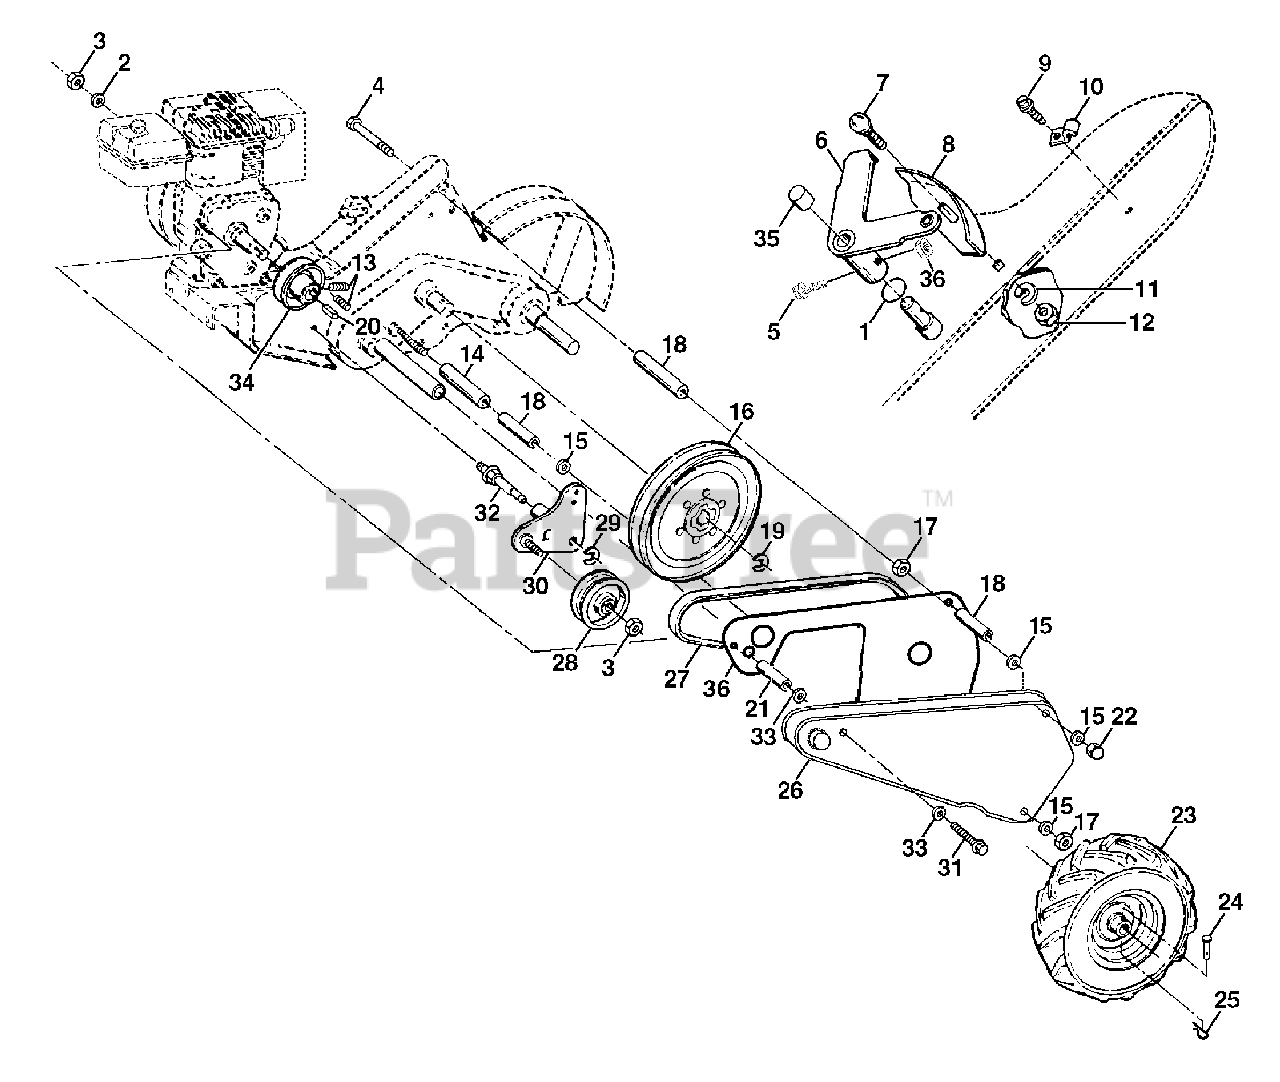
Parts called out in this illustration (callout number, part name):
2	Washer, Lock 3/8
3	Nut, Hex 3/8-16
4	Bolt, Hex Head 5/16-18 x 4-1/2
6	Lever, Shift
7	Bolt, Carriage 1/4-20 x 1/2 Grade 5
8	Plate, Shift Indicator
9	Screw, Hex Washer Head, Slotted #10-24 x 1/2
11	Washer, Lock 1/4
12	Nut, Hex 1/4-20
13	Screw, Set, Hex 5/16-18 x 3/8
14	Spacer, Split
15	Washer 11/32 x 11/16 x 16 Gauge
16	Sheave, Transmission
17	Nut, Hex 5/16-18
19	Ring, Retainer
20	Key, Square
21	Spacer, Split .523 x .718 x 2
22	Nut, Cap 5/16-18
23	Rim
23	Tire Valve
24	Rivet, Drilled
25	Clip, Hairpin
26	Guard, Belt
28	Pulley, Idler
29	Ring, Klip
30	Bracket, Idler
31	Bolt, Hex Head 1/2-20 x 2-3/4
32	Shaft, Idler Arm
33	Washer
34	Sheave, Engine
35	Cap, Plunger
36	Nut, Lock #10-24 UNC
